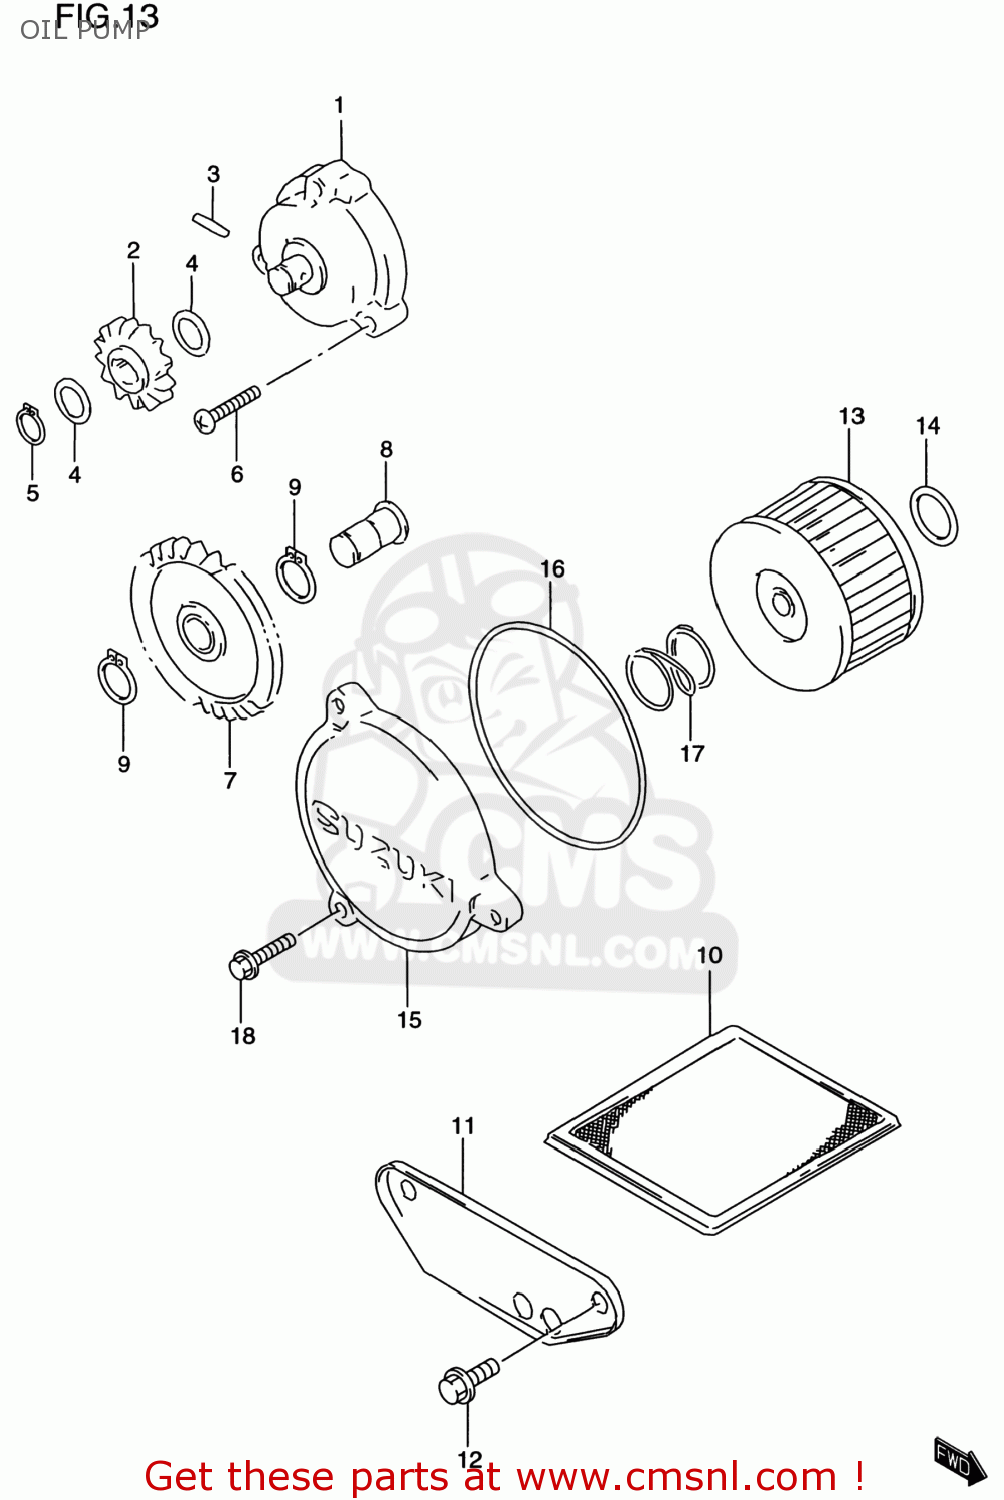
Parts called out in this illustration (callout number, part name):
1	PUMP ASSY,ENGINE OIL
2	GEAR,ENG OIL PUMP DRIVEN
3	PIN(4X15.8)
4	SHIM
5	CIRCLIP,10MM
6	SCREW
7	GEAR,OIL PUMP DRIVE(NT:30)
8	SHAFT,ENGINE OIL PUMP DRIVE
9	CIRCLIP,12 MM
10	STRAINER,ENGINE OIL
11	CAP,OIL STRAINER
12	BOLT 6X12
13	FILTER,ENGINE OIL
14	O RING(D:2.4,ID:15.8)
15	CAP,OIL FILTER
16	O RING(D:2.4,ID:73)
17	SPRING
18	BOLT
